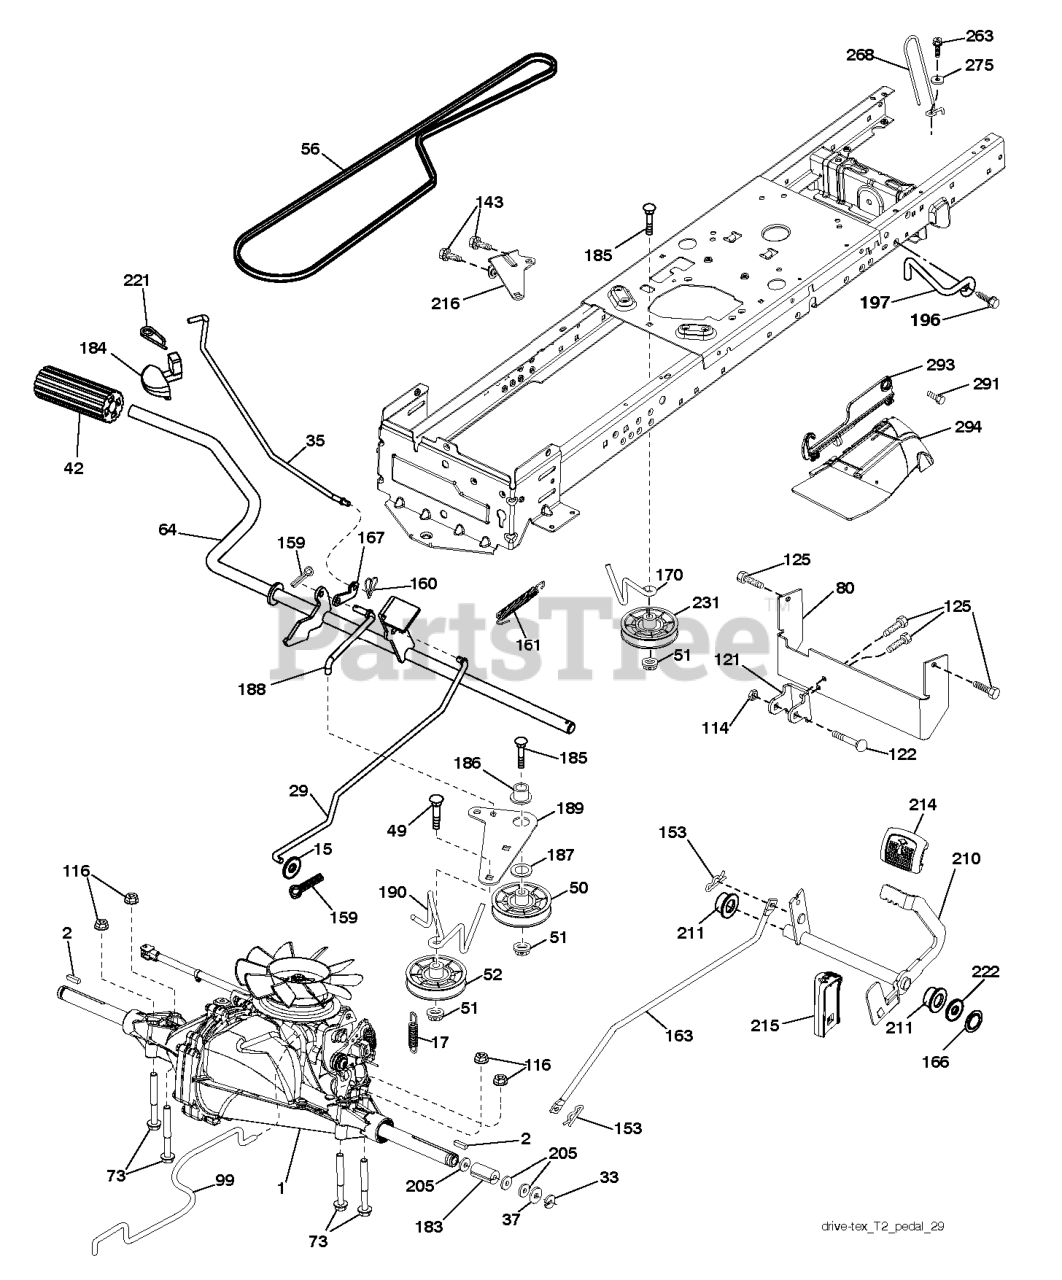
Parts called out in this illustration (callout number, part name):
2	SQUARE KEY
15	WASHER
17	SPRING.BRAKE.HG3000/3500
29	ROD.BRAKE.T2.TEX
35	ROD.CNTRL.PARK.PREDATOR.LT.TEX
42	PEDAL COVER T
50	IDLER.FLAT.910.OFFSET
51	NUT LOCK FLG 3/8-16 UNC
52	IDLER.V-GROOVE.910.OFFSET
64	SHAFT.ASM.PEDAL.BRK.CNTR
73	BOLT HEX 5/16-18 GR 5
80	STRAP.TORQUE.T2
99	ROD.ASM.BYPASS.SPRING.T2.FS
114	NUT.71038.31-18.HEX.NYLOCK
116	NUT LOCK HEX FLANGE 5/16-18
121	BRACKET STRAP TORQUE
122	BOLT.5/16-18X2.5
125	SCREW
143	Screw 5/16-18 x 1/2 Hex, Self Tapping 5/16-18 x 1/2
153	RETAINER M
159	COTTER PIN
160	RETAINER CLIP
161	SPRING, RETURN LT
163	ROD.CONTROL.PCH.T2.TEX
166	NUT.PUSH.625
167	LATCH.BRAKE.SPRING
170	KEEPER.CENTER SPAN.1.688
183	SPACER, AXLE PVST
184	HANDLE PARKING BRAKE
186	SPACER.RETAINER
187	WASHER 12/32X2X10GA
188	RP.LINK.CLUTCH.GROUND.DRIVE
189	BELLCRANK.GROUND.DRIVE.TEX.
190	KEEPER.BELLCRANK.DRIVE
196	SCREW 3/8-16X1
197	LINK.CLUTCH.ANIT-ROTAT
210	ROCKER.ASM.PEDAL.CONTR
211	BEARING.NYLON
214	PEDAL.FORWARD.PAD.TEX
215	PEDAL.REVERSE.TEX.GT.4
216	BRACKET.PULLEY.IDLER.W/TEX
221	RETAINER.SPRING.CLIP.H
222	WASHER 21/32 X 1-1/4 X 10 GA.
231	IDLER.V-GROOVE.1.688.OFFSET
263	SCREW, 3/8-16X3/4
268	GUARD MUFFLER
275	WASHER
291	SHOULDER BOLT 5/16-18TT
293	HINGE RIGHT
294	GUARD RIGHT
